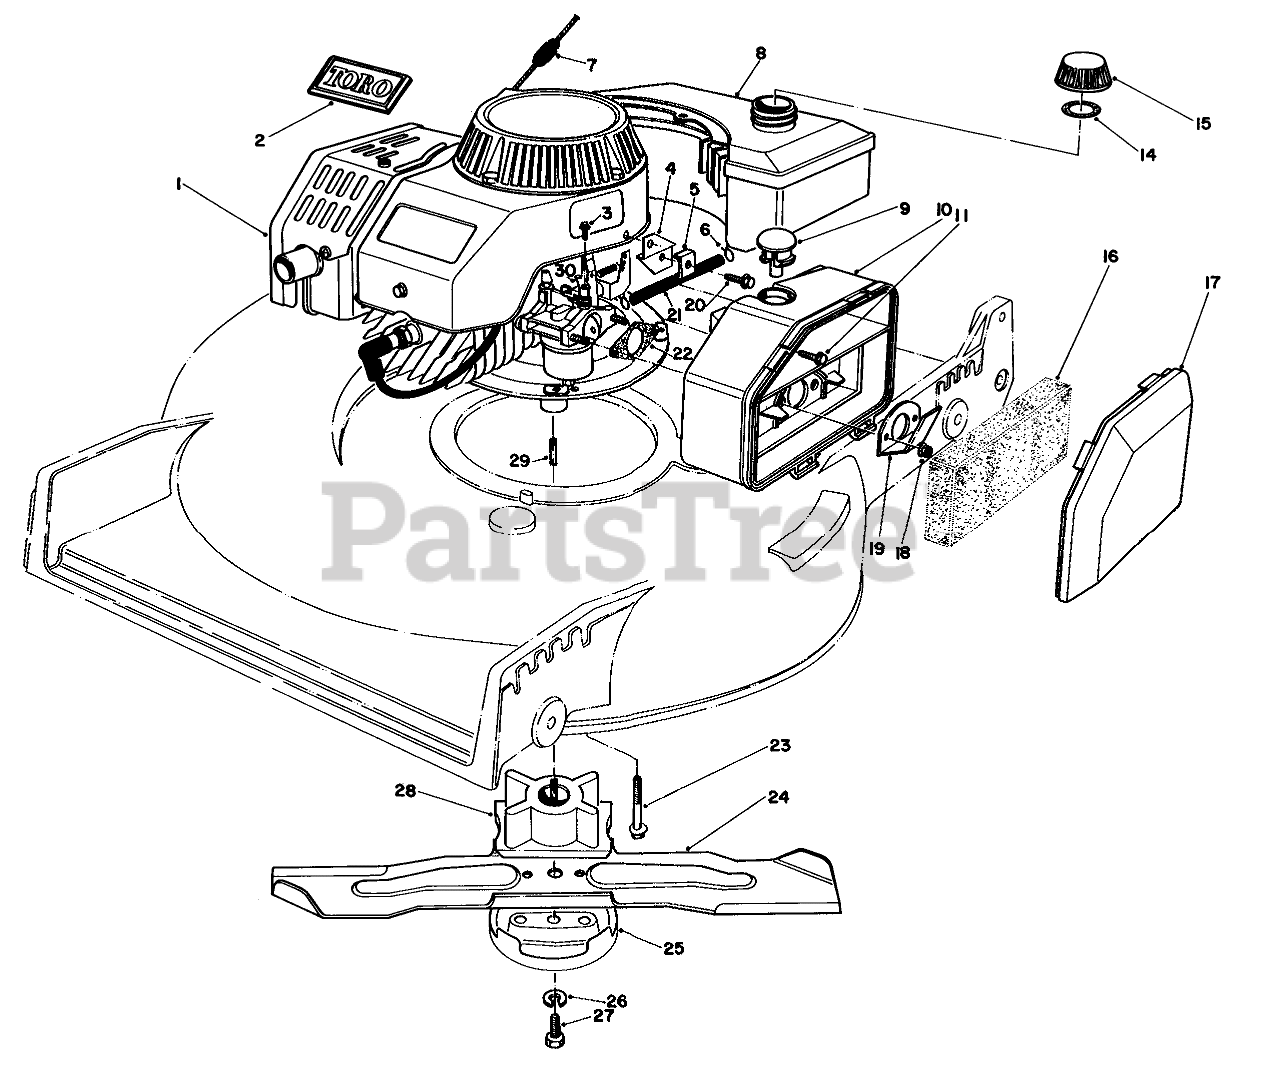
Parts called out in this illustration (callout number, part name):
1	Engine (Incl. Ref. #2)
2	TORO LOGO PLT
3	TAPPING SCREW
4	Carrier-Cable
5	CLAMP-CABLE
6	CLAMP-HOSE
7	STOP-ROPE
8	Gas Tank Assembly
9	Plug-Button
10	AIR CLEANER
11	Screw-Hex Head
14	GAS CAP GASKET
15	Gas Cap Assembly (Incl. Ref. #14)
16	FILTER
17	AIR CLEANER COVER
18	M6 X 1 LOCKNUT
19	SPIT BACK DEFLECTOR
20	Screw
21	FUEL LINE
22	GASKET-AIR CLEANER
23	SCREW-HHF
24	BLADE-21in
25	Anti Scalp Cup
26	WASHER-LOCK
27	SCREW-BLADE
28	Retainer Blade
29	KEY-SQUARE
30	CHOKE LEVER
